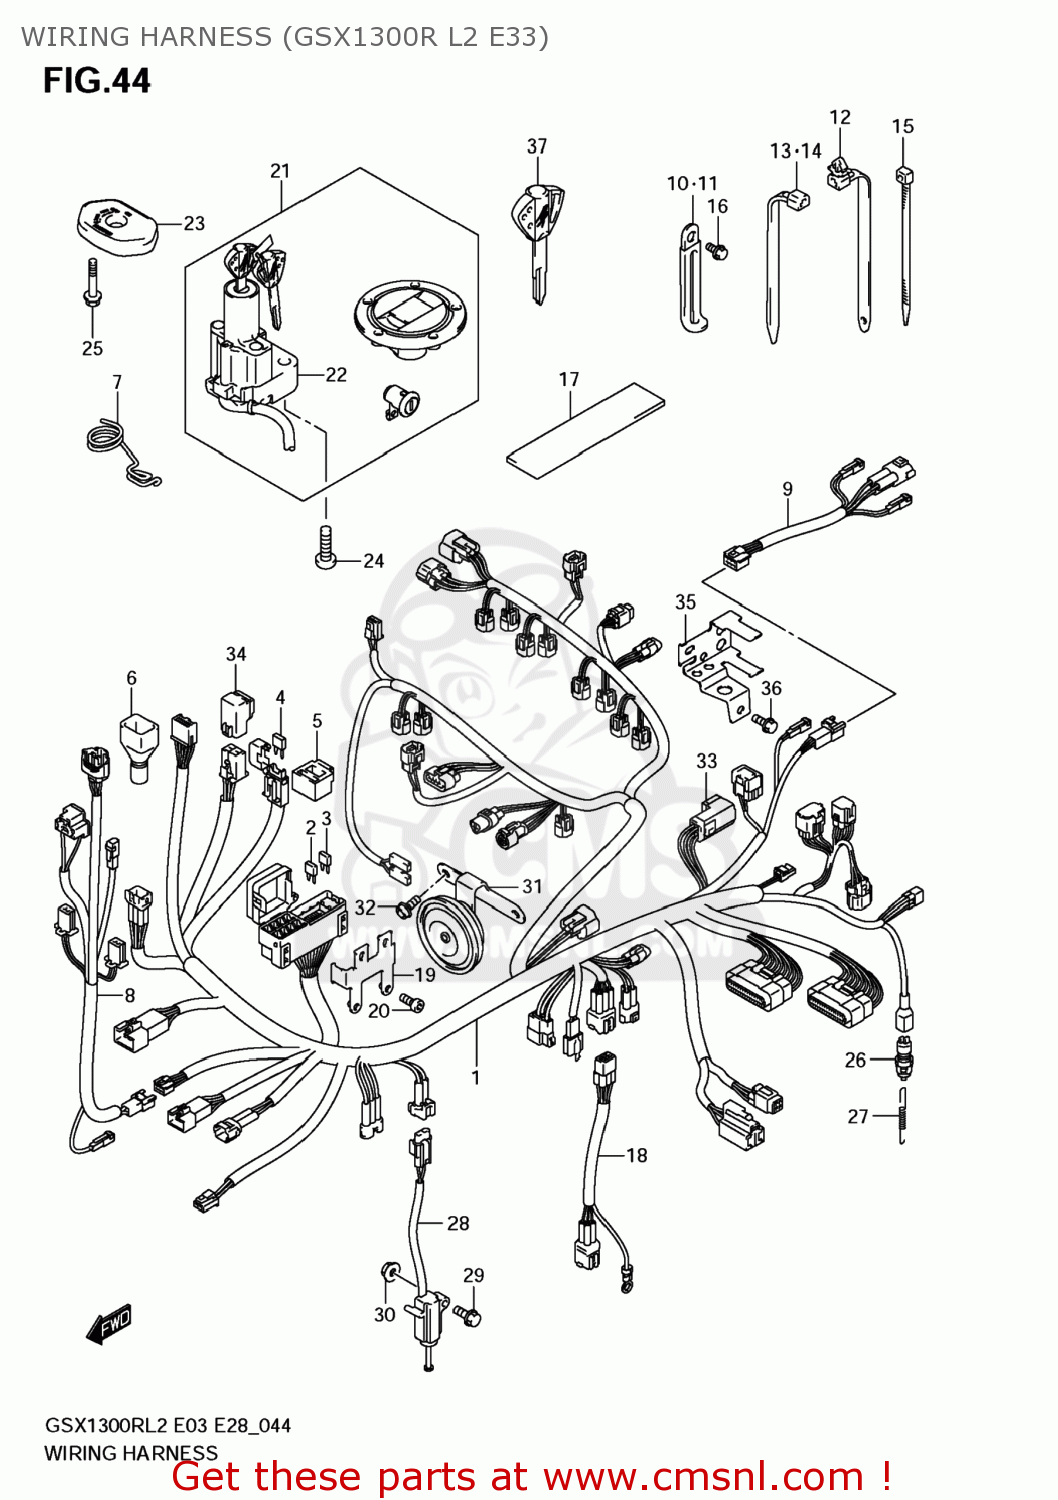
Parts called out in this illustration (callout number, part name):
1	HARNESS,WIRING
2	FUSE(10A)
3	FUSE(15A)
4	FUSE(15A)
5	HOLDER,FUSE
6	COVER,SPEEDOMETER COUPLER
7	GUIDE,WIRING HARNESS
8	HARNESS,WIRING NO.2
9	WIRE,RR COMB
10	CLAMP(L:45)
11	CLAMP(L:135)
12	CLAMP(L:120)
13	CLAMP(L:125)
14	CLAMP(L:165)
15	CLAMP(L:145)
16	BOLT
17	PROTECTOR,WIRING HARNESS
18	WIRE,O2 SENSOR
19	BRACKET,FUSE BOX
20	BOLT
21	LOCK SET
22	LOCK ASSY,STEERING
23	COVER,STEERING LOCK
24	BOLT(8X20)
25	BOLT
26	SWITCH ASSY,STOP LAMP
27	SPRING
28	SWITCH ASSY,SIDE STAND
29	BOLT(8X35)
30	NUT
31	HORN ASSY
32	BOLT
33	RELAY ASSY
34	RELAY ASSY
35	BRACKET,FUEL PUMP RLY
36	BOLT
37	KEY,BLANK
